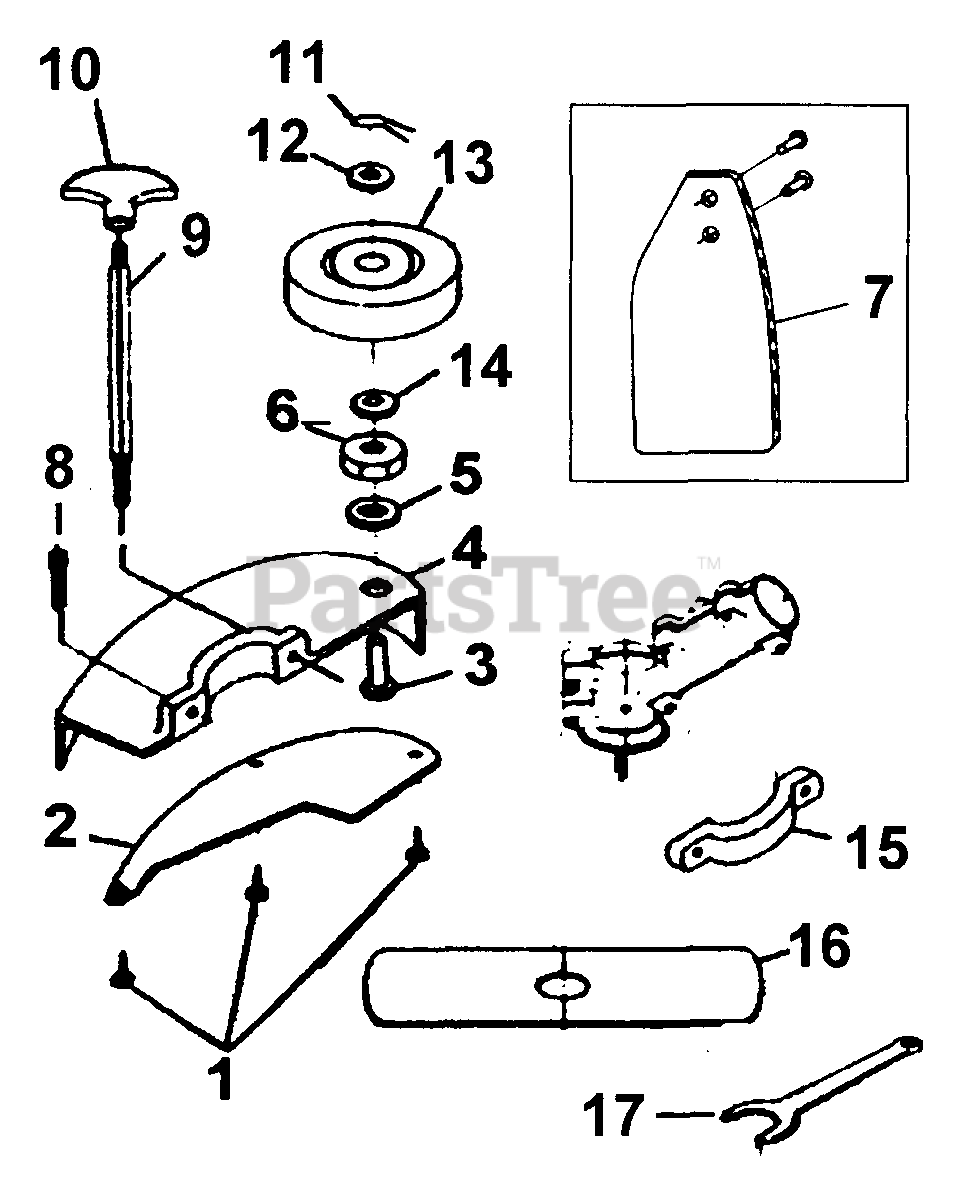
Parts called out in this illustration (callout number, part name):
1	SCREW, SELF TAPPING
3	EDGER AXLE
4	GUARD
6	NUT
7	DRAG FLAP KIT
8	BOLT, ALLEN HEAD
9	SHAFT & KNOB ASSY.
11	COTTER PIN
16	EDGER BLADE
17	SPANNER WRENCH
